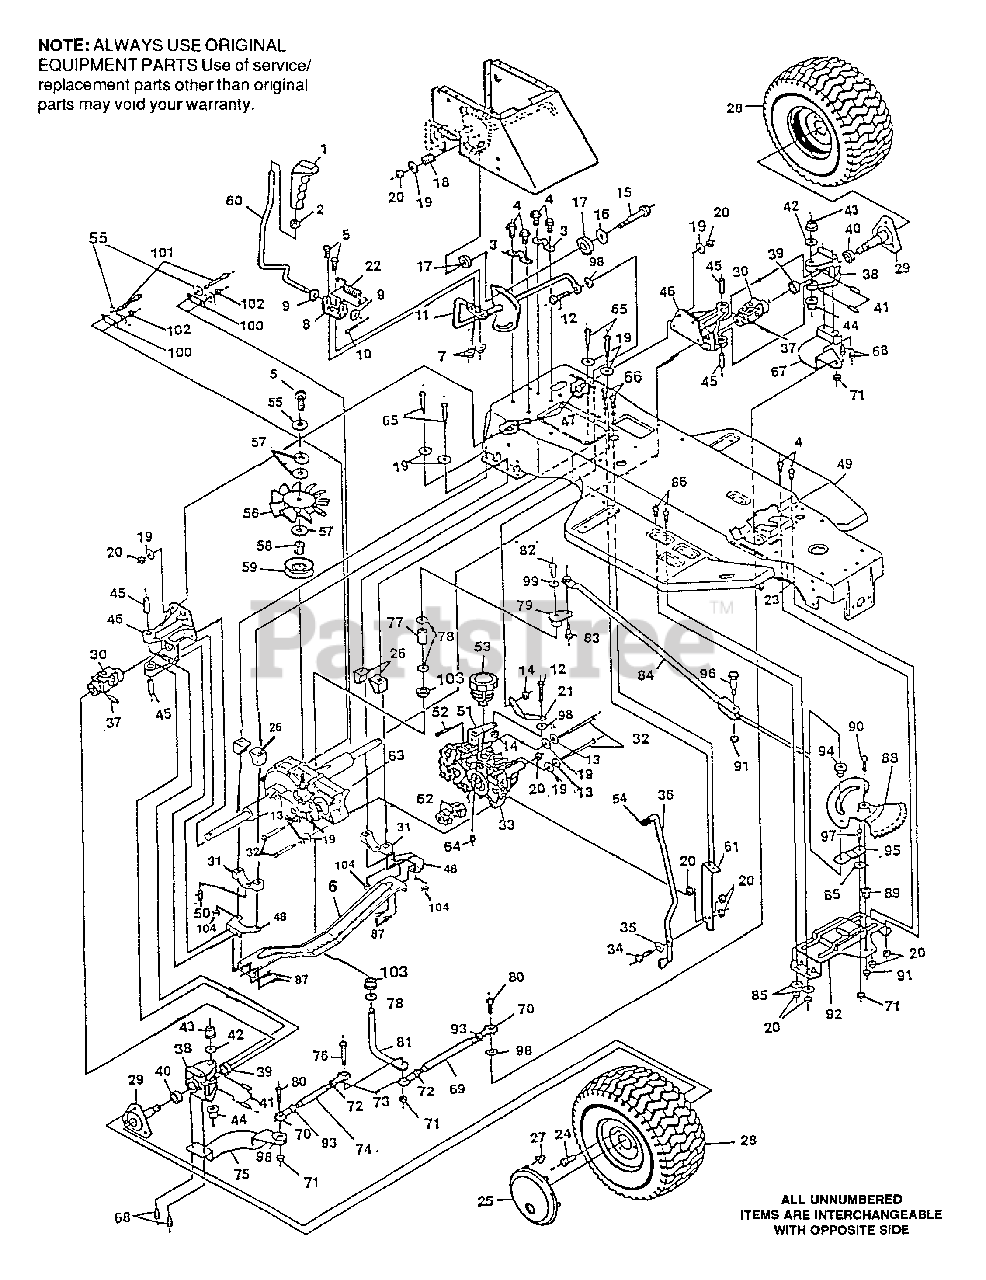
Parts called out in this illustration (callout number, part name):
1	Handle, Deck Engage Lever
2	Nut, 1/2-13
3	Bracket, Clutch/Brake Arm
4	Screw, 5/16-18 x 1/2 In
5	Screw, 1 /4-20 x .62 In.
7	Nut, 1/4-20
8	Bracket, Shift
9	Washer, Flat
10	Pin, Cotter
11	Shift Rod Assembly
12	Screw, 3/8-16 x 1-1/4 In.
14	Nut, 3/8-16 Thd
15	Screw, 5/16-18 x 2 In.
16	Washer, Flat
17	Washer, Friction
19	Washer, Flat
20	Nut, 5/16-18 Thd.
21	Shift Link
22	Spring, Torsion
23	Trim
24	Screw, Hx Hd, 1/2-20 x 1/2 In.
25	Hubcap, 8 In.
26	Mounting Block
27	Clip, Hubcap
28	Tire and Wheel Assembly Tire
28	Wheel
28	Valve System
29	Hub Assembly
30	U-Joint Assembly
30	Grease Fitting
31	Mounting Block
32	Screw, 5/16-18 x 4-1/2 In.
33	Hydrostatic Pump
34	Shoulder Bolt
35	Washer
36	Rod- Relief Valve
37	Pin, Grooved, 1/4 x 1 1/2 In.
38	Bracket, Steering Pivot, Outer
41	Pin, Spring 1/4 x 1 1/2 In.
42	Washer, Flat
43	Bushing, Shouldered
44	Bushing, Shouldered
45	Pin, Steering Hinge
46	Bracket, Steering Pivot, Inner
47	Screw, Hx Hd, 5/16-18 x 1 In.
48	Bracket, Transaxle Mounting
49	Main Frame
50	Screw, #10-32 x 1/4 In.
51	Armspeed Control
52	Pin, Spring
53	Reservoir, Hydro
54	Cap, Memory Rod
55	Washer, Split Lock
57	Washer, Flat
58	Nut, Pulley 1/2-20 and 1/4-20
59	Pulley, Assy Hydro
61	Stabilizer Bracket
63	Transaxle
65	Screw, 5/16-18 x 2 25 In.
66	Screw, 5/16-18 x 5/8 In.
67	Arm, Rear Wheel Steer, L.H.
68	Screw, Self-Tap 3/8-16 x 1 In.
69	Tie Rod, L.H.
70	Tie Rod, End L.H.
71	Nut, Hex, Ctrlk, 3/8-24
72	Nut, Hex Jam, 3/8-24
73	Tie Rod End R.H.
74	Tie Rod, R.H.
75	Arm, Rear Wheel Steer, R.H.
76	Screw, 3/8-24 x 1 3/4 In.
78	Washer, Lat 49/64 In.
79	Steering Pivot
80	Screw, 3/8-24 x 1 1/4 In.
81	Shaft, Steering Pivot
82	Screw 5/16-24 x 1 In.
83	Bolt, Shoulder 3/8-24
84	Rod Assembly, Rear Wheel Steer
85	Washer, Flat 3/8 In.
86	Screw, Self-Tap 5/16-18 x 3/8 In.
87	Screw, Self-Tap 5/16-18 x 5/8 In.
88	Assembly Sector Gear
89	Bushing, Sector Gear
90	Screw, 1/2-20 x 2 3/8 In.
91	Nut, Hx, Ctrlk 1/2-20
92	Plate, 4-Wheel Steer Pivot
93	Nut, Jam 3/8-24
94	Cam Yoke Roller
95	Arm, Roller Swing
96	Shoulder Bolt, Cam Roller
97	Shoulder Bolt, Cam Follower Arm Pivot
98	Washer, Split Lock
99	Washer Flat
100	Bracket, Rear Pivot
101	Screw 1/4-20 x .75 In.
102	Nut 1/4-20
103	Bearing Spindle
104	Nut, 5/16-18
